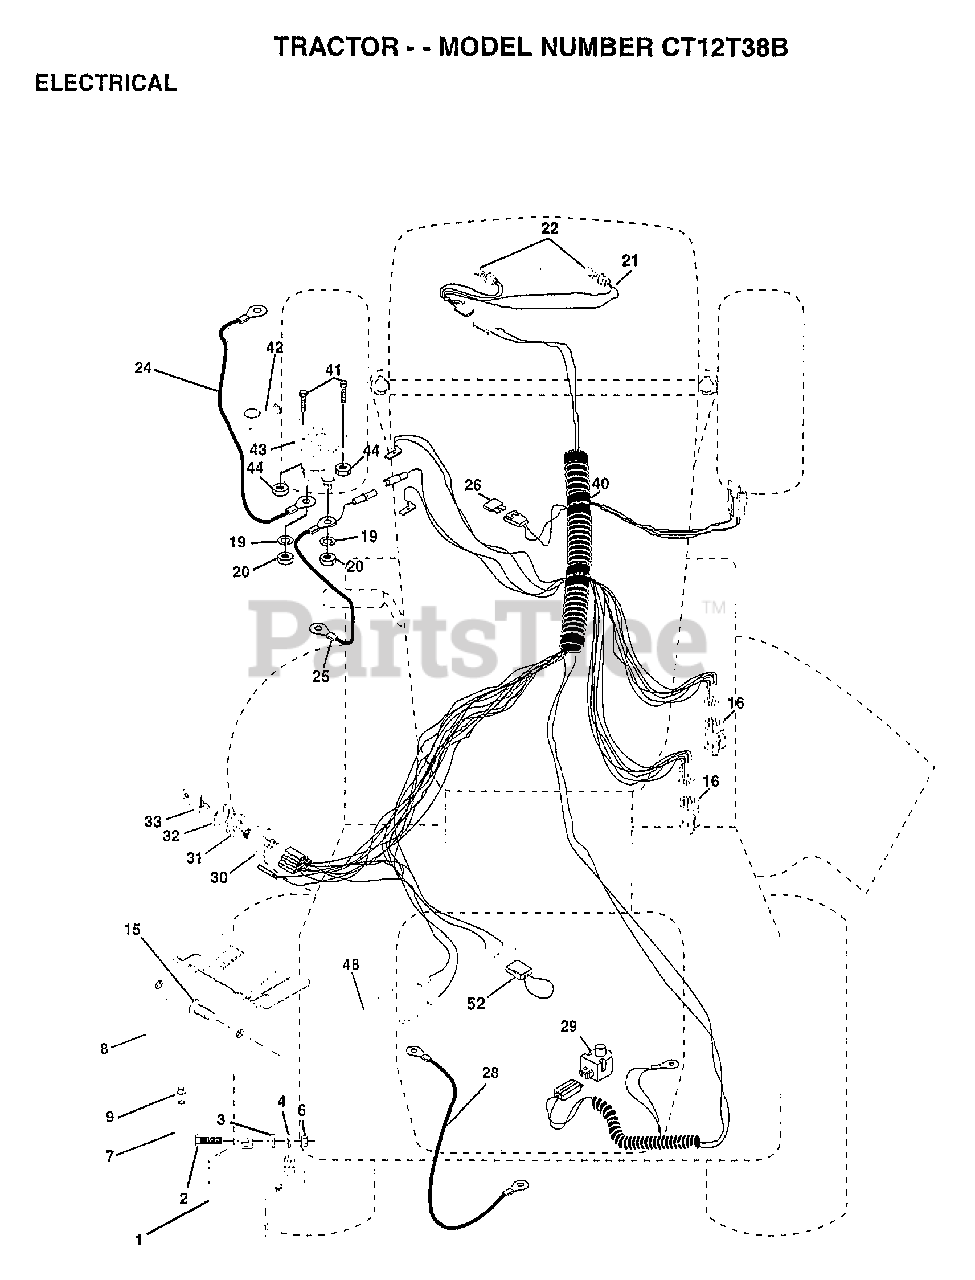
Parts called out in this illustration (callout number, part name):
2	BOLT LT
3	WASHER
4	LOCKWASHER
7	TUBE T
8	"CASE,BATTERY.MECH"
9	HOSE CLAMP T
15	FASTNER.SNAP-IN
16	SWITCH INTERLOCK
20	NUT
21	"HARNESS,LIGHT SOC"
22	HEADLAMP BULB
24	CABLE ASM.
25	CABLE.BTRY.6GA.RD
26	FUSE HYT
28	CABLE T
29	SWITCH SEAT
30	SWITCH IGN 4POS
31	NUT IGNITION
32	COVER KEY SWITCH
33	KEY
40	HARNESS-IGNITION
41	BOLT HXHD FIN
44	NUT HXKEP 1/4X20
48	ADAPTER AMMETER
52	PROTECTION LOOP
